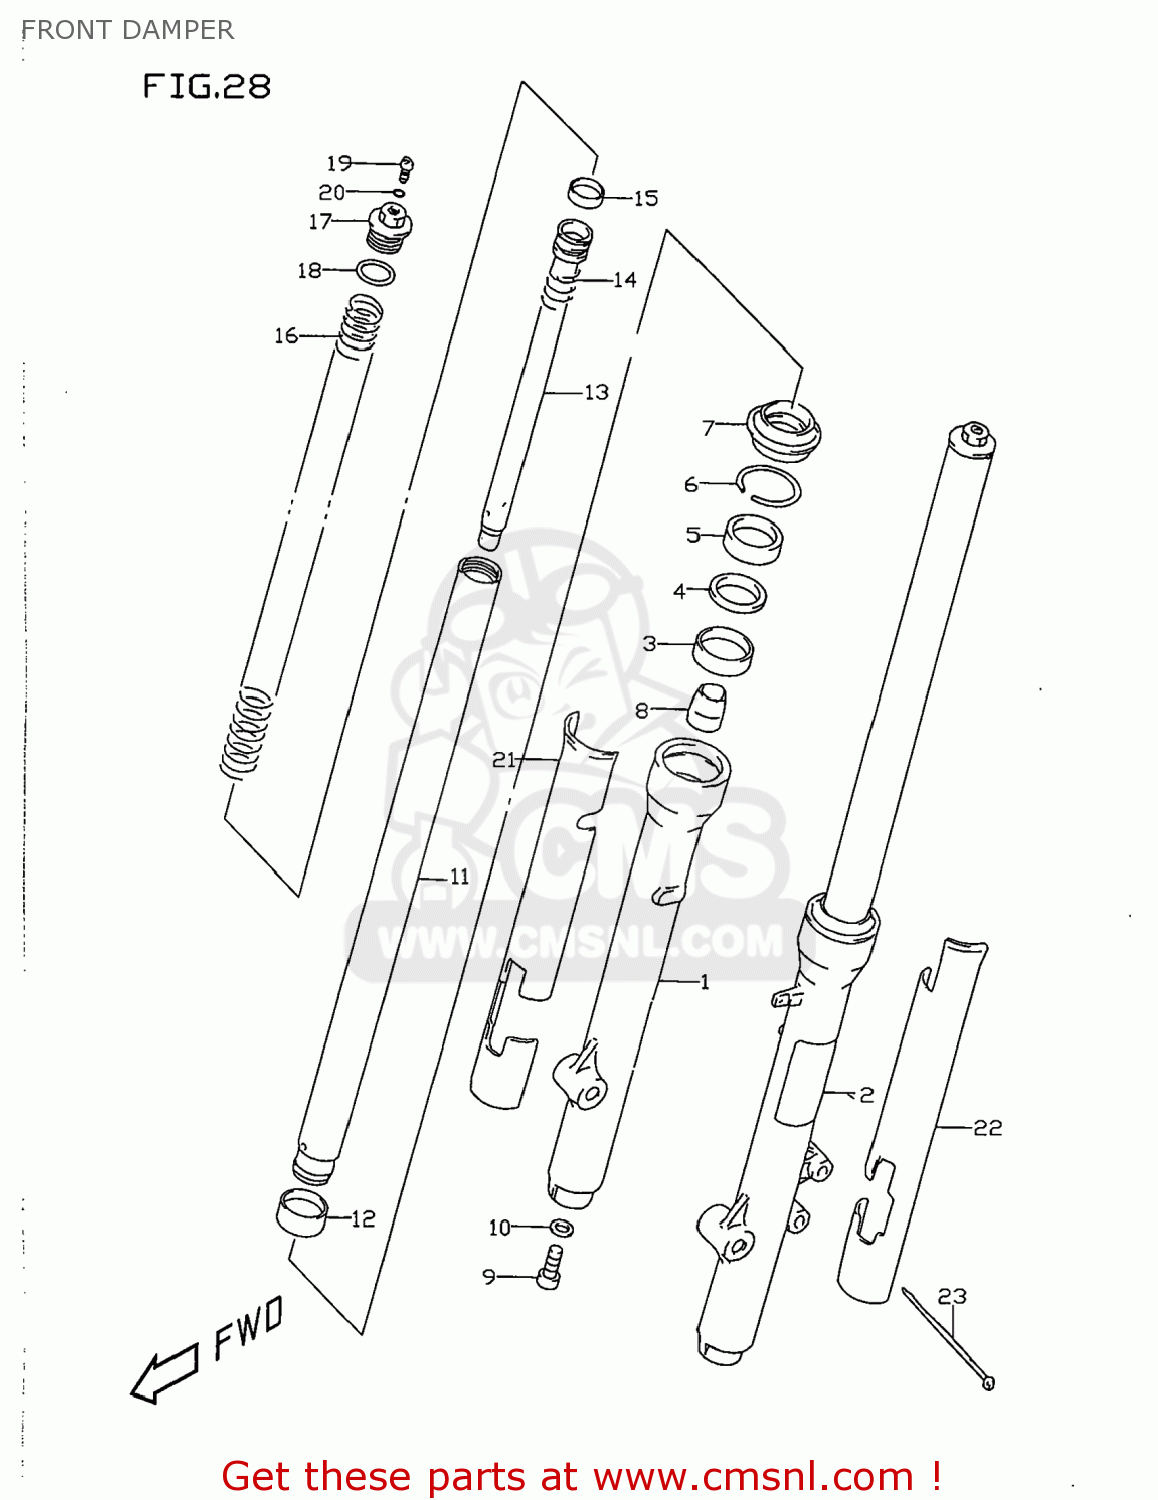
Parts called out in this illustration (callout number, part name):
1	TUBE,OUTER,R
2	TUBE,OUTER,L
3	BUSH,GUIDE
4	SPACER,SEAL
5	SEAL,OIL 35X48X11
6	RING,OIL SEAL STOPPER
7	SEAL,DUST
8	PIECE,OIL LOCK
9	BOLT(8X27)
10	GASKET (NAS)
11	TUBE,INNER
12	PISTON
13	SEAT,UNDER
14	SPRING,REBOUND
15	RING,PISTON
16	SPRING,UNDER
17	BOLT,FORK
18	O RING
19	BOLT,PLUG
20	O RING
21	PROTECTOR,FR FORK,R
22	PROTECTOR,FR FORK,L
23	CLAMP(L:250)
